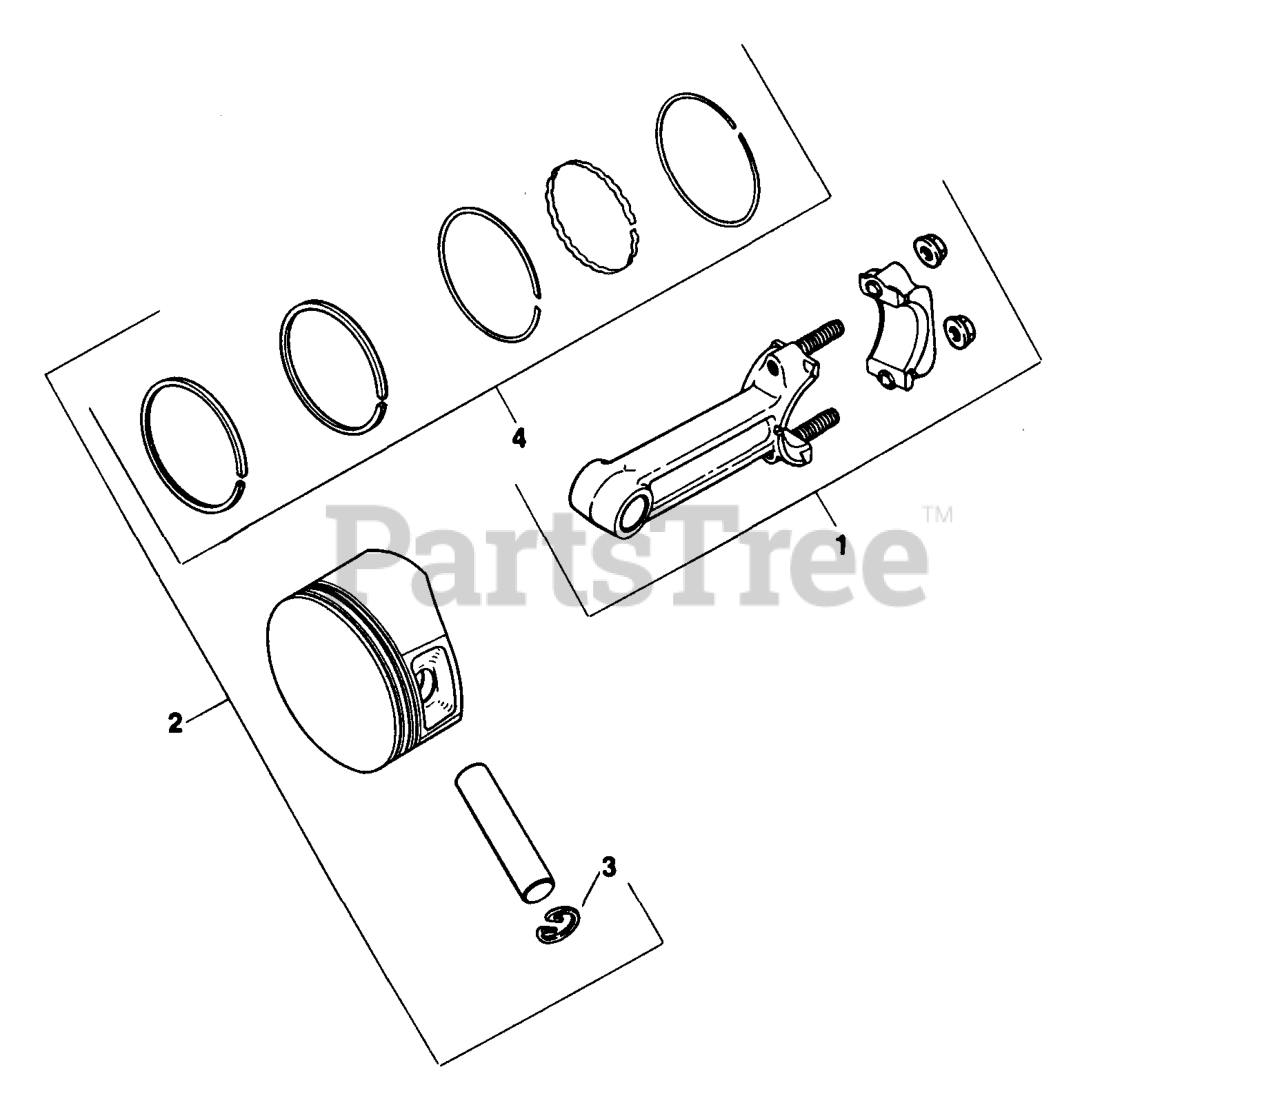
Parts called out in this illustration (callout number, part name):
1	ROD STD. - DISCONTINUED
1	ROD .010 - DISCONTINUED
2	KIT, PISTON W/RING SET STD
2	KIT, PISTON W/RING SET .003 - DISCONTINUED
2	KIT, PISTON W/RING SET .010-(#DSC)
2	PISTON W/ RINGSET .020 - DISCONTINUED
2	KIT, PISTON W/RING SET .030 - DISCONTINUED
4	RINGS STD.
4	RINGS .010
4	RINGS .020
4	RINGS .030 - DISCONTINUED
